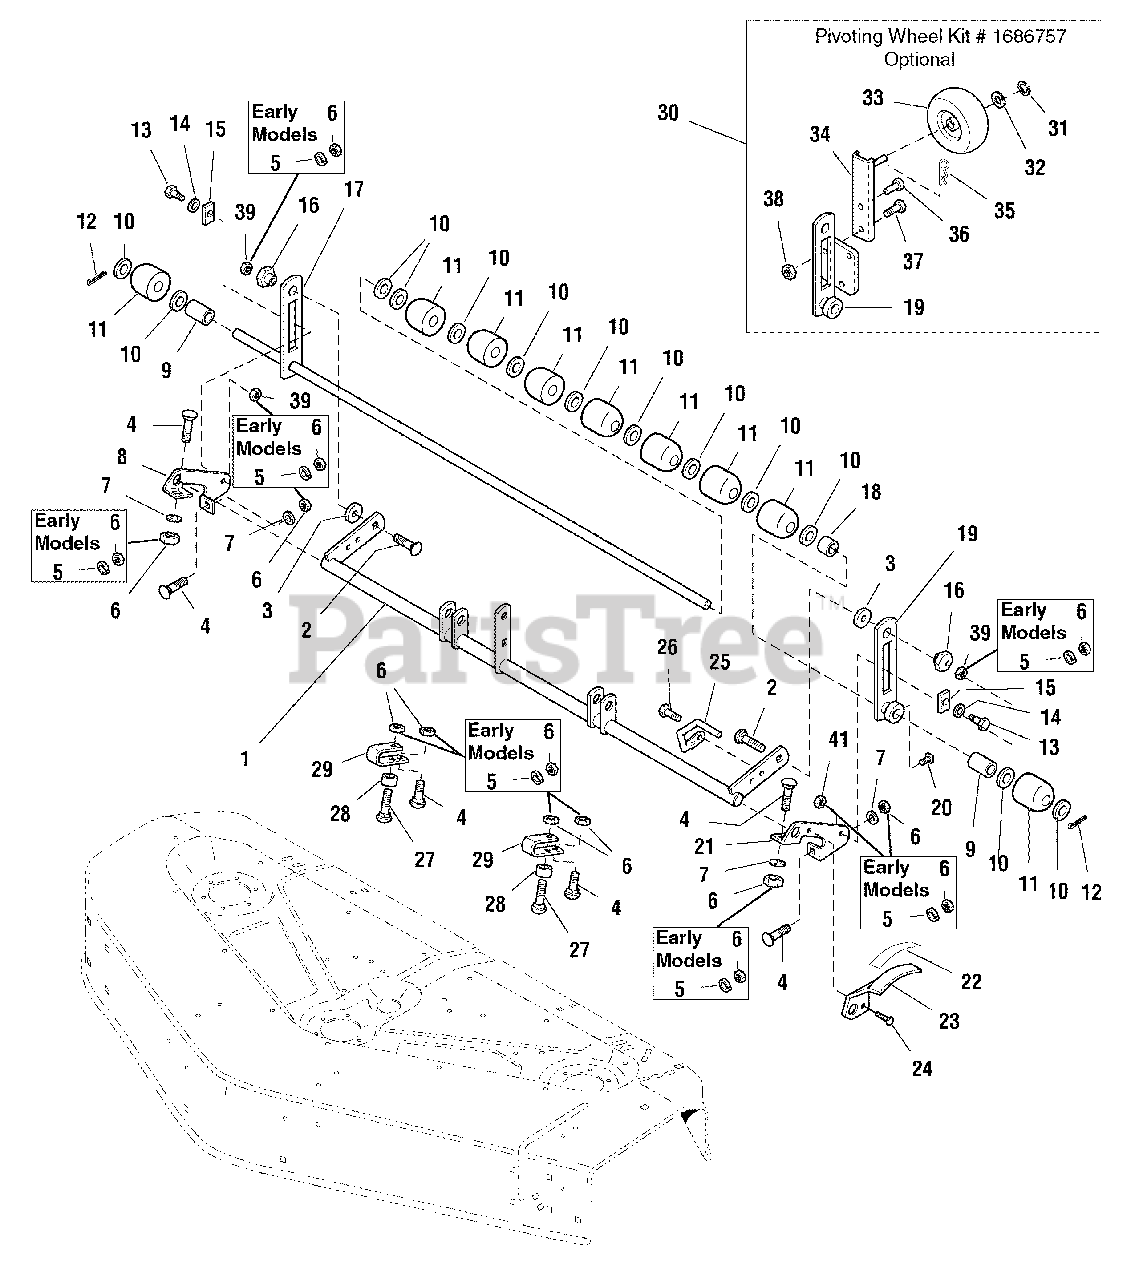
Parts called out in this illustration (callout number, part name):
1	ROCKER SHAFT ASSEMBLY
2	CARRIAGE BOLT, 3/8-16 x 1-3/4
3	WASHER, 3/8
4	CARRIAGE BOLT, 3/8-16 x 1
5	LOCKWASHER, 3/8 (Early Models)
6	NUT, Hex, Full, 3/8-16 (Early Modles)
6	NUT, Hex Lock, ESNA, 3/8-16 (Later Models)
7	WASHER, Plain, 3/8
8	BRACKET, Roller, RH
9	SPACER, Long
10	WASHER, 1.0
11	ROLLER, Outer
12	PIN, Cotter
13	BOLT, Shoulder, 3/8-16 X 1.34
14	WASHER, 1/2 x 1-1/4
16	NUT, Hex Adjusting, .99 DIA .687
17	BAR & SHAFT ASSEMBLY, Roller
18	SPACER, Short
19	BAR ASSEMBLY, Roller, LH
19	*BAR ASSEMBLY, Roller, LH (Included in Service Kit Ref. No. 32)
20	SET SCREW, Square Head, 5/16-18 x 1/2, G8
21	BRACKET, Roller, LH
22	DECAL, Cutting Height Indicator
23	PLATE, Height Indicator
24	CAPSCREW, Hex Head, Taptite, 1/4-20 x 3/8
25	ROD, Indicator
26	CAPSCREW, Hex Head, Taptite, 5/16-18 x 1/2
27	CARRIAGE BOLT, 3/8-16 x 2-1/4
28	SPACER
30	KIT, 48" Mower Slide Wheel (Includes Ref. Nos. 21*, 33-40)
31	E-RING, 1/2
32	WASHER, Flat, 1/2 x 7/8
33	WHEEL, Slide
34	BAR ASSEMBLY, Wheel
35	HAIRPIN
36	HITCH PIN, 3/8
37	CAPSCREW, Hex Head, 3/8-16 x 1
38	NUT, Hex, Nylon Lock, 3/8-16
39	NUT, Toplock Spiral Flange, 3/8-16
